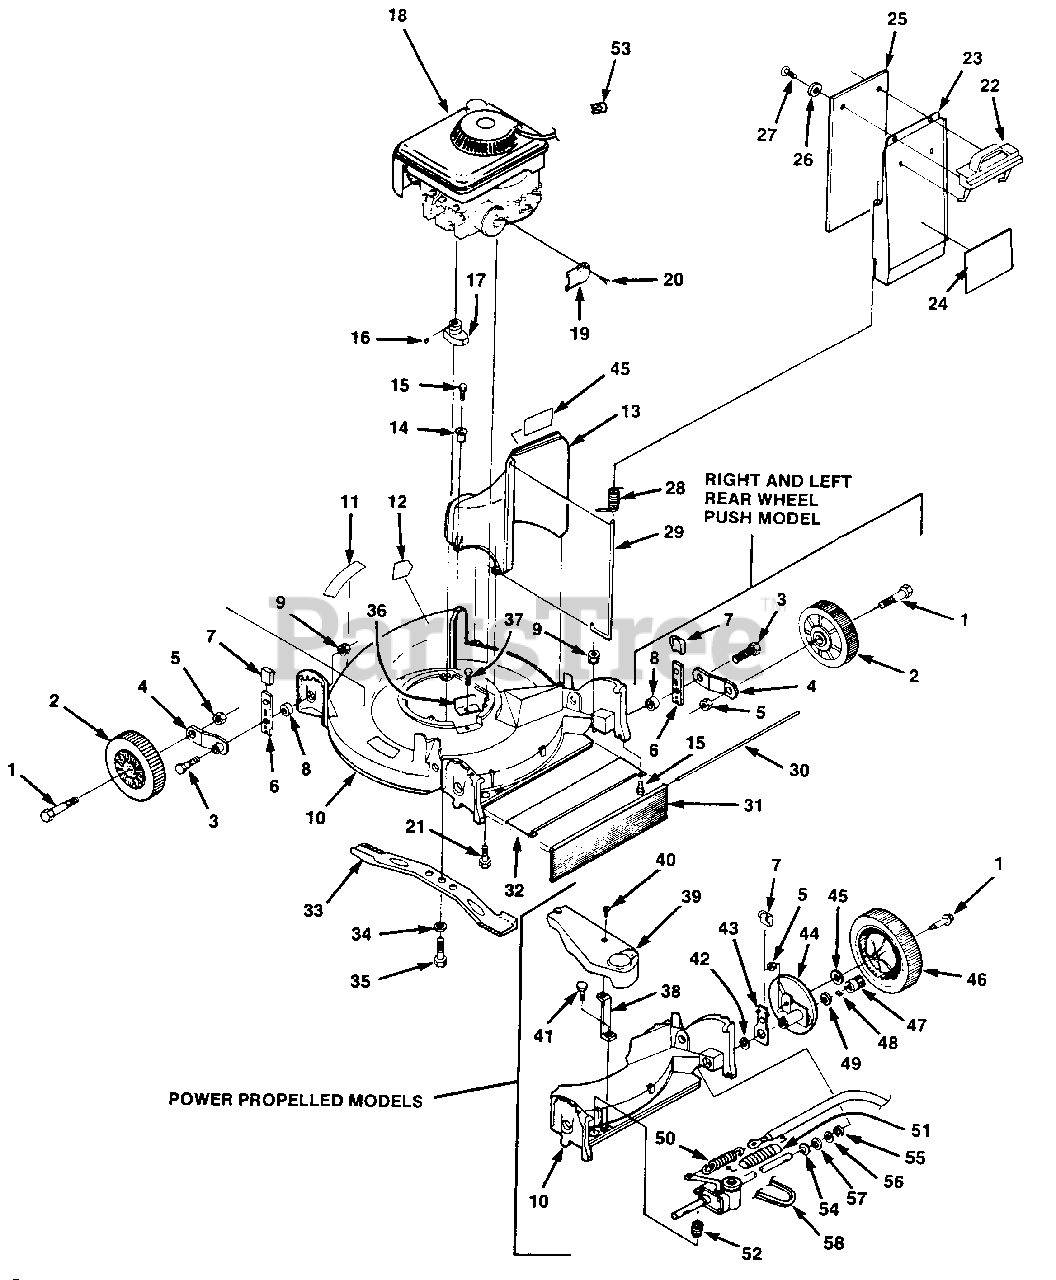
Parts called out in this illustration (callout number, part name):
1	BOLT- Axle
2	WHEEL & TIRE
3	BOLT- Hex hd. 5/16-18
4	ARM- Wheel hgt. adj.
5	NUT- Hex 3/8-24
6	SPRING- Index
7	KNOB- Indexing spring
8	SPACER- Indexing spring
9	NUT- Flange 5/16-18
10	DECK- 21"
11	DECAL- Product ident.
12	DECAL- Warning
13	CHUTE- Discharge
14	EYELET- Simpson
15	SCREW- Hex hd. (1/4-20 x 3/4")
16	KEY- 5/8 x 5/32
17	ADAPTER- Blade
18	ENGINE- 3.5 HP
19	DEFLECTOR- Muffler
20	SCREW- Hex hd. 8-32 x 3/8"
21	SCREW- 5/16-18 x 1
22	HANDLE- Door
23	DOOR- Chute
24	DECAL- Door
25	DAMP- Flap
26	WASHER- Flat 1/4"
27	SCREW- (Rd. Hd. 1/4-10 x 5/8")
28	SPRING- Door
29	PIN- Hinge
30	ROD- Drap flap
31	FLAP- Drag
32	COVER- Rear
33	BLADE- 21"
34	WASHER- Lock 7/16"
35	BOLT- Shoulder
36	COVER- Belt opening
37	SCREW- (Hex hd. 1/4-20 x 1/2")
39	COVER- Drive
40	SCREW- (Rd. Hd. 1/4-20 x 3/4")
41	SCREW- (Hex hd. 10-16 x 1/2")
42	SPACER- Hgt. Adj.
43	SPRING- Index
44	DRIVE WHEEL SUPPORT
45	WASHER- Flat
46	WHEEL & TIRE (drive)
47	PINION- R.H.
48	PAWL- Pinion
49	WASHER- Flat
50	SPRING- Traction lever
51	COVER- Spring
52	SPRING- Compression
53	STOP- Rope
54	RING- Eaton
55	WASHER- Flat
57	WASHER- Shim
58	BELT- Drive
